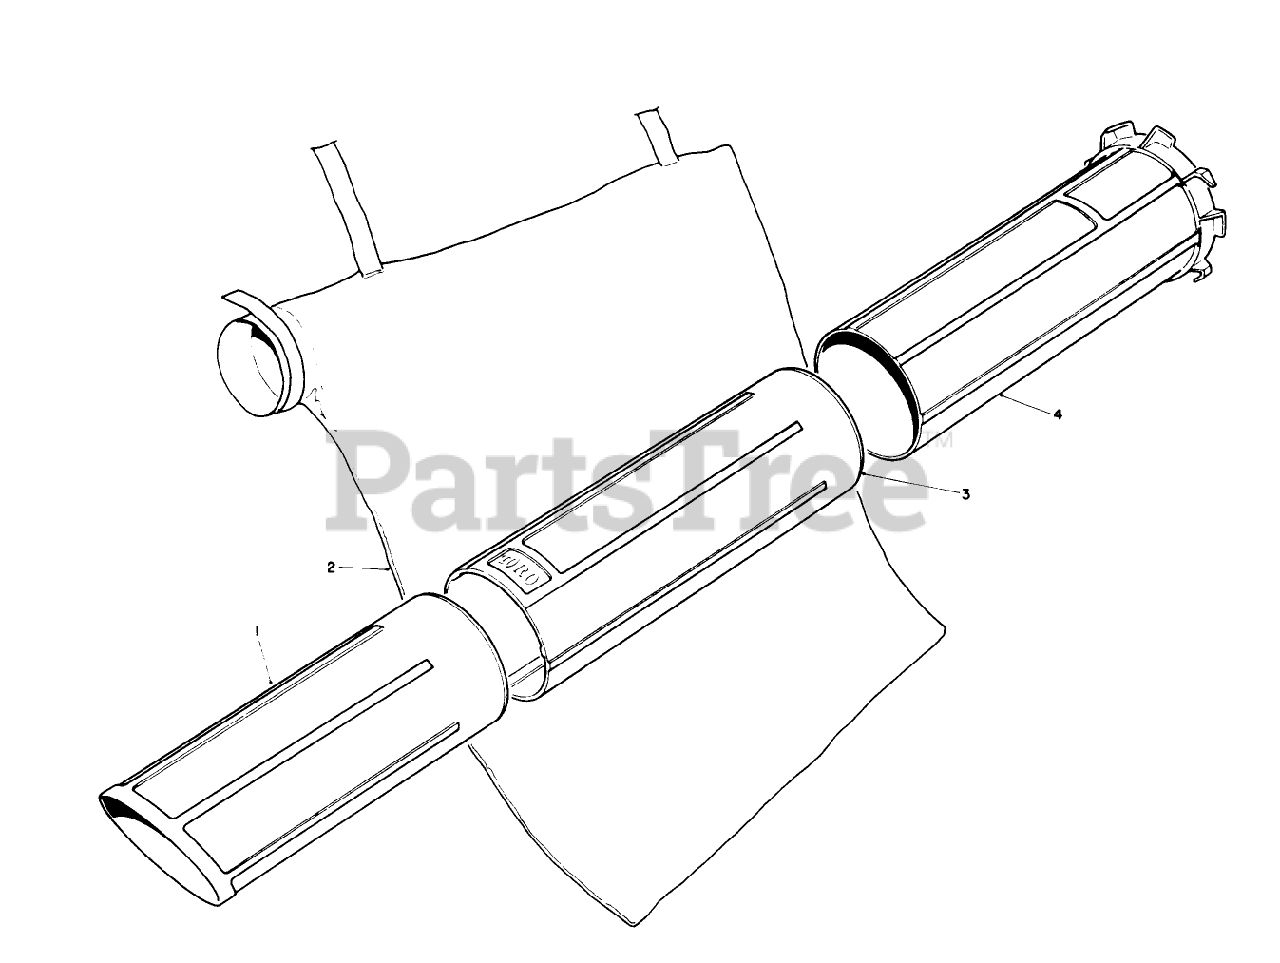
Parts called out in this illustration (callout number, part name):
1	LOWER VAC TUBE
2	VACUUM BAG
3	MIDDLE VAC TUBE
4	Tube-Vacuum, Upper
